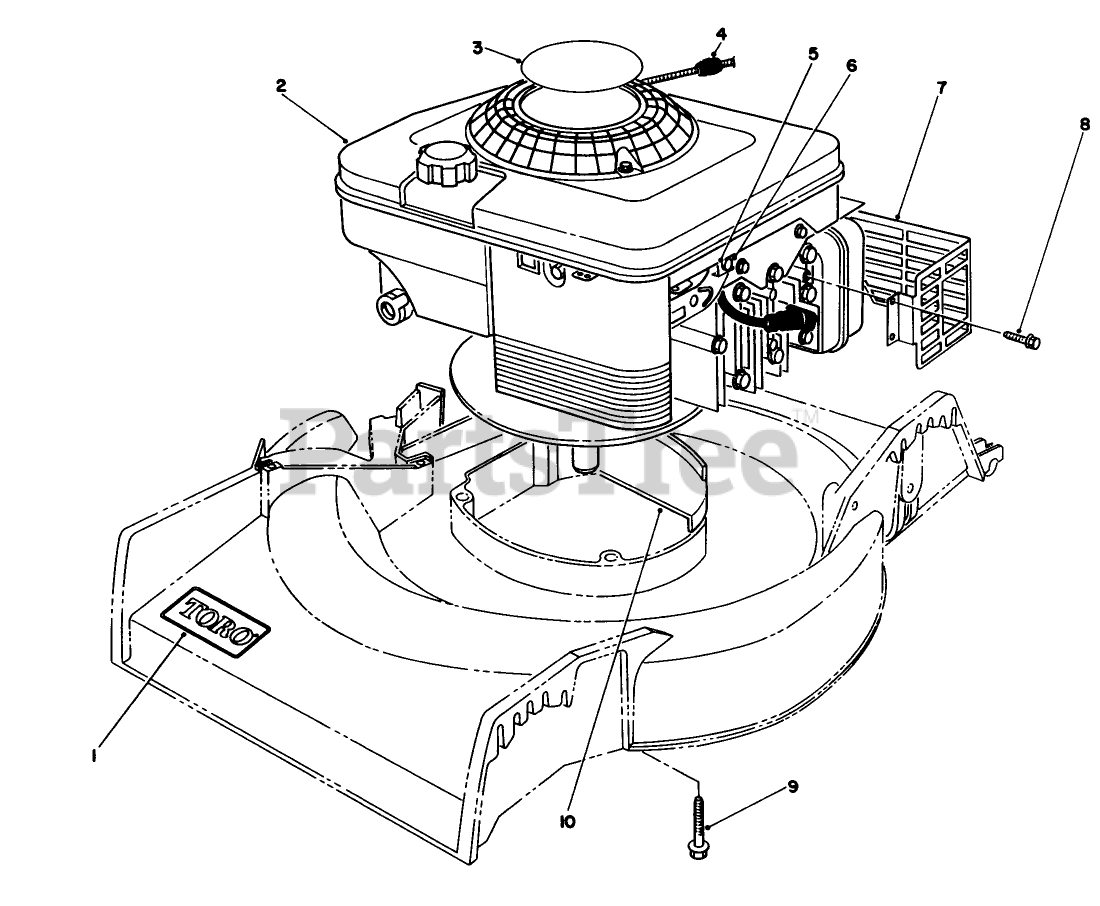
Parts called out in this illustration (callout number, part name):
1	DECAL
2	Engine
4	STOP-ROPE
5	CLAMP-CASING
9	THD FORM SCREW
10	HOUSING CAP
